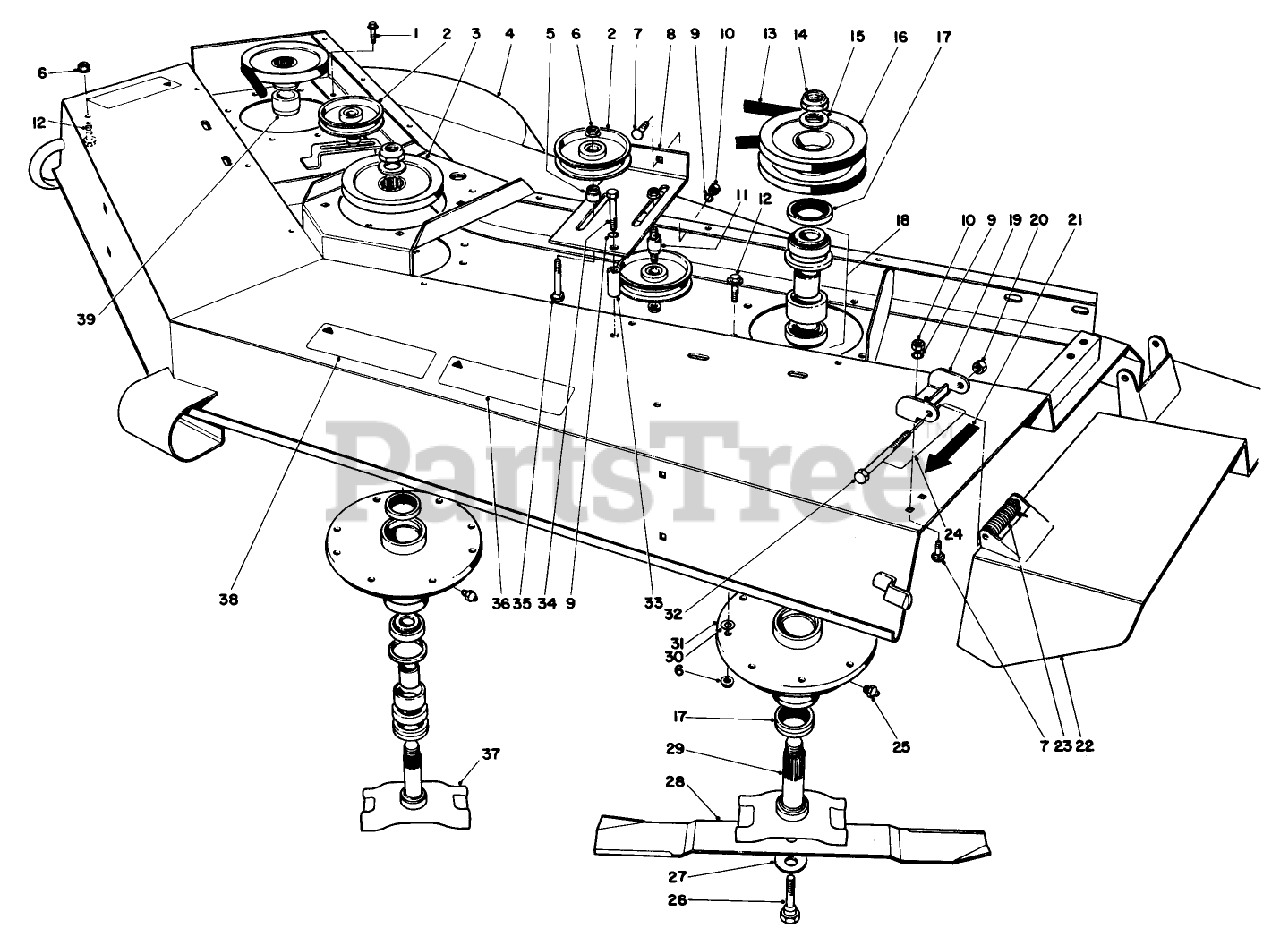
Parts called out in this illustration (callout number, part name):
1	SCREW-HHF
1	Caster Arm R.H.(Incl. Ref.#29)
2	PULLEY-IDLER
2	SCREW-HH
3	PULLEY AND HUB ASM
3	WASHER-FLAT
4	Cutter Deck
4	CHAIN
5	SPACER-IDLER PULLEY
5	RH DECK COVER R
6	NUT-HF
6	NUT-HEX
7	SCREW-CARR
7	WASHER-LOCK
8	Idler Mount L.H.
8	Bracket-Clamp
9	WASHER-LOCK
9	Shroud Universal
10	NUT-HEX
10	PIN-COTTER
11	STUD-IDLER
11	SHACKLE
12	SCREW-HHF
12	PIN-CLEVIS
13	V-BELT
13	Lift Strap
14	NUT-LOCK, NI
14	NUT-HEX
15	WASHER-THRUST
15	WASHER-LOCK
16	PULLEY-L.H. W.A.
16	SCREW-HHF
17	SEAL-OIL
17	LH DECK COVER R
18	BEARING ASM
18	WASHER-FLAT
19	Bracket-Hinge
19	NUT-HH
20	NUT-HEX
20	WASHER-LOCK
21	DECAL - BLADE LINE
21	WASHER-FLAT
22	Deflector
22	SCREW-CARR
23	SPRING
23	NUT-LOCK, NI
24	WARNING DECAL
24	Bracket-Clamp
25	FITTING-GREASE
25	Bar-Caster Clamp
26	CAPSCREW
26	SCREW-HH
27	WASHER-BELLEVILLE
27	PIN-LYNCH
28	BLADE-STANDARD, LH, 25IN
28	SPACER 1/2 IN
29	OUTER SPINDLE WA
29	Bushing
30	WASHER-FLAT
30	FITTING-GREASE
31	Spindle Housing
31	Caster Arm L.H. (Incl. Ref.#29)
32	SCREW-HH
32	WASHER-THRUST
33	SPACER-IDLER MOUNT
33	Caster Fork Rear
34	SCREW-HH
34	AXLE ASM
35	SCREW-CARR
35	WASHER
36	DECAL-CAUTION, BLADE
36	BEARING RETAINER
37	Spindle Ctr.
37	SPANNER BUSHING
38	Decal-Caution
38	WHEEL
39	Spacer R.H.Spindle
39	ROLLER BRG W/46-8960
